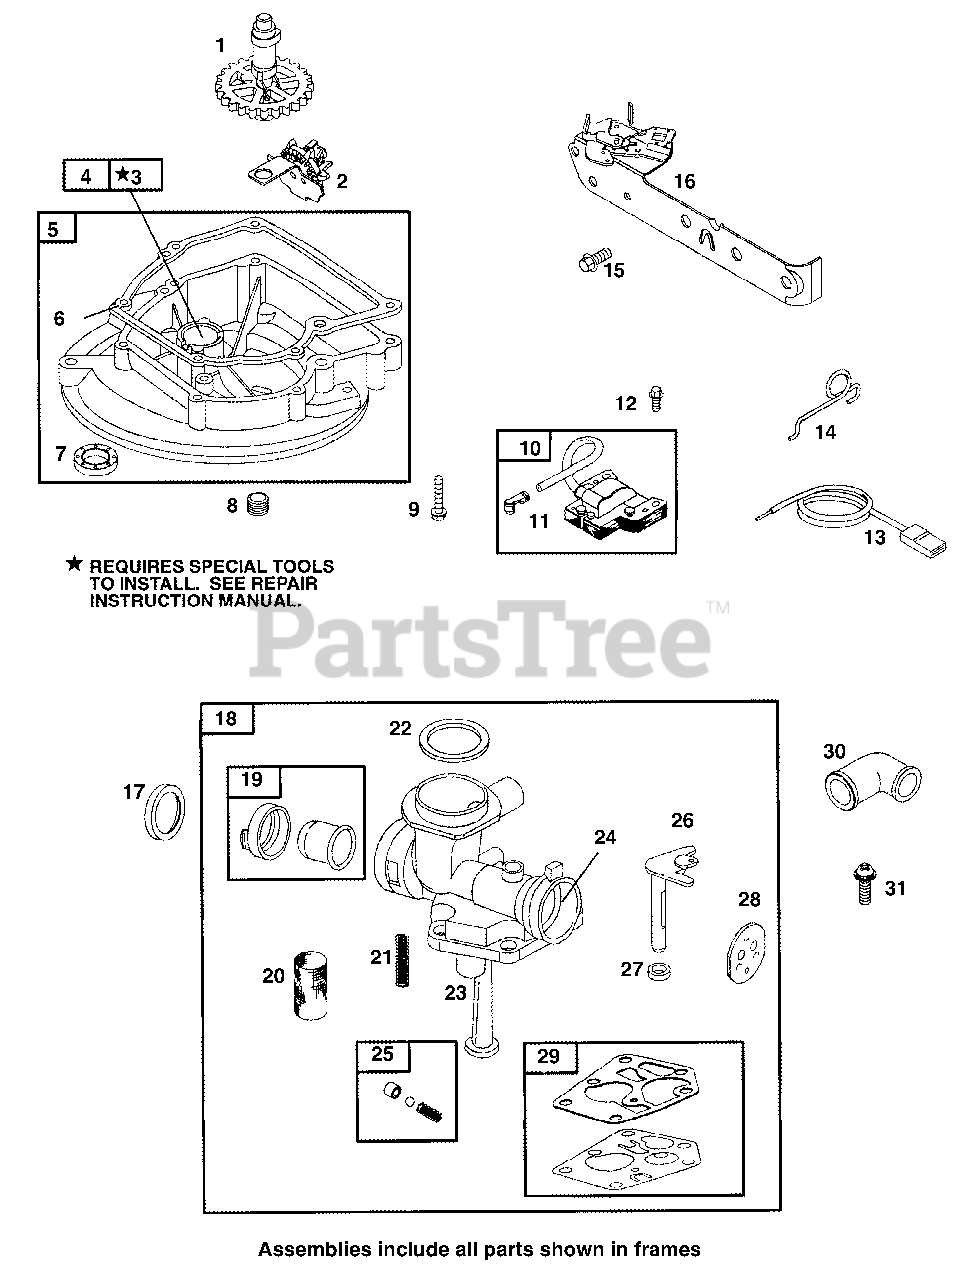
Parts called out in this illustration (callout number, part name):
1	Cam Gear (Clockwise)
2	Oil/Governor Slinger
4	Oil Seal
5	Engine Sump
6	Crankcase Gasket
7	Oil Seal
8	Oil Drain Plug
9	Hex Screw
10	Magneto Armature
11	Cable Terminal
12	Hex Screw
13	Stop Wire
14	Air Vane Link
15	Hex Screw
16	Control Bracket
17	Trim Ring (Primer Bulb)
18	Carburetor
19	Carburetor Primer
20	Carburetor Screen
21	Choke Diaphragm Spring
22	Air Cleaner Gasket
23	Pickup Tube
24	Intake Manifold Seal
25	Check Valve Seat
26	Throttle Shaft
28	Throttle Valve
29	Carburetor Diaphragm
30	Grommet
31	Screw Phillips
